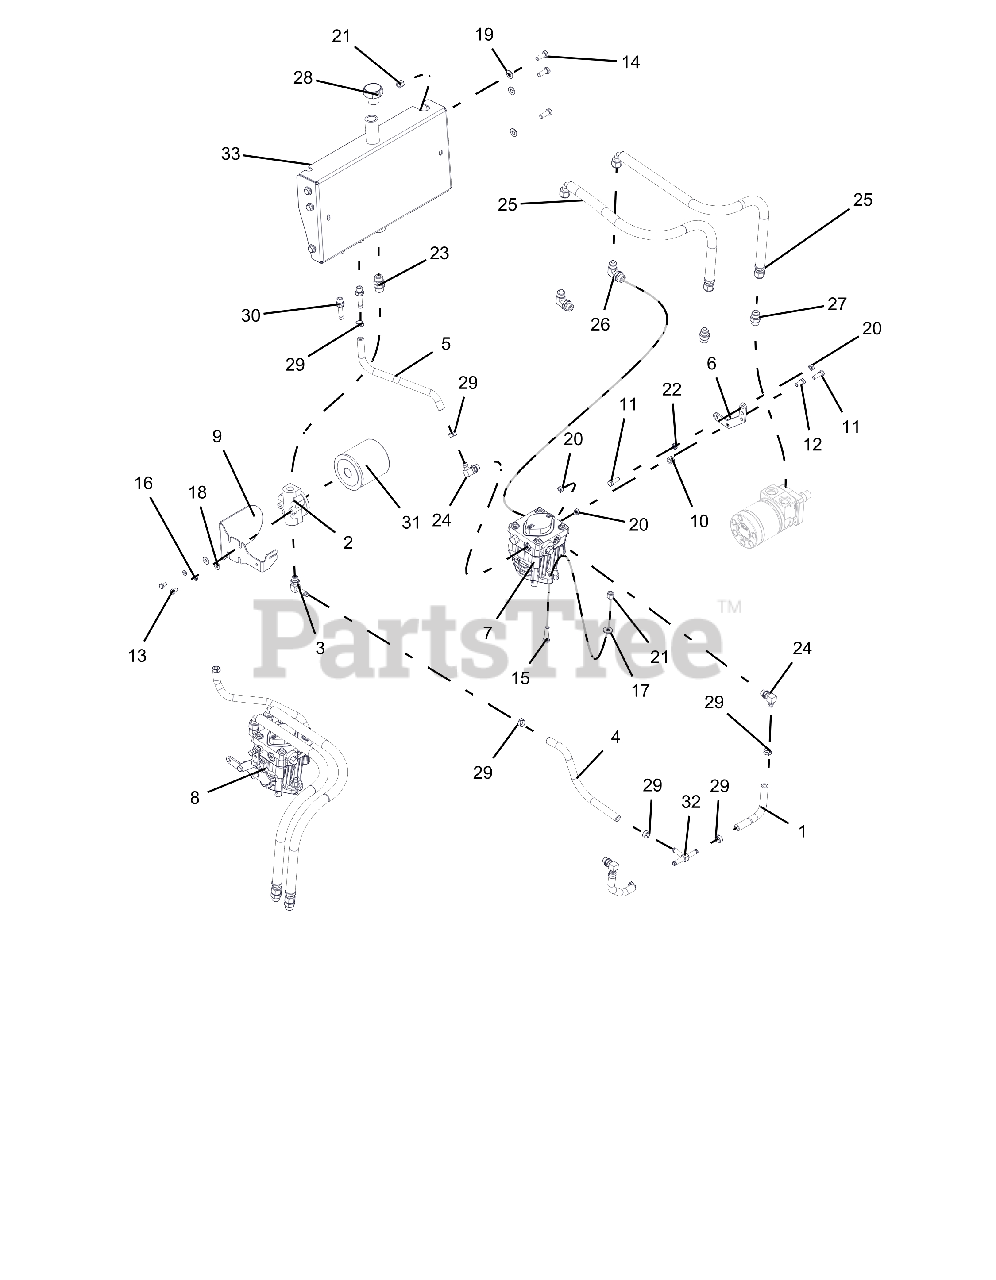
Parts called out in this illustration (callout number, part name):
1	HOSE, HYD 3/8 X 6.00
2	HEAD, OIL FILTER
3	FTG, 90 BRB-OR 4601-06-08
4	HOSE, HYD .375X10.5
5	HOSE, HYD .375X14.00
6	BRACKET-PUMP CONTROL-BLACK
7	PUMP, LH HYD PE
8	PUMP, RH HYD PE
9	GUARD, HYDRO FILTER-RED
10	BSHG, SLV REV
11	BLT-HEX .31-18X1.00 GR5 YWZC
12	BLT-HEX .31-18X.75 GR5 YWZC
13	BLT-HEX .25-20X.50 GR5 YWZC
14	BLT-HEX .38-16X1.00 GR5 YWZC
15	BLT-HEX .38-16X1.50 GR5 YWZC
16	WSHR-LK .25X.062 REG YWZC
17	WSHR-FL-STL.38X.875X.083 YWZC
18	WSHR-FL-STL.312X.734X.065 YWZ
19	WSHR-FL-STL.406X.812X.065 YWZ
20	@NUT-LK-CTR-JAM .31-18 YWZC
21	NUT-LK-NYL .38-16 YWZC
22	NUT, JAM .312-18 YWZC
23	FTG, STR UNION M80-M80
24	FTG, 90 9/16MOR X 3/8HOSE SHRT
25	HOSE, HYD 1/2 X 26 1/2 EZFLEX
26	FTG, ADP JIC-ORB 6801-08-08
27	FITTING, STRAIGHT
28	CAP, OIL FILL BREATHER
29	CLAMP, HOSE - 1/2" PINCH
30	ADAPTER, STRAIGHT FITTING
31	FILTER, OIL
32	FTG, TUN 3/8 HOSE
33	WLDMT, TANK HYDRO STR PORT-RED
